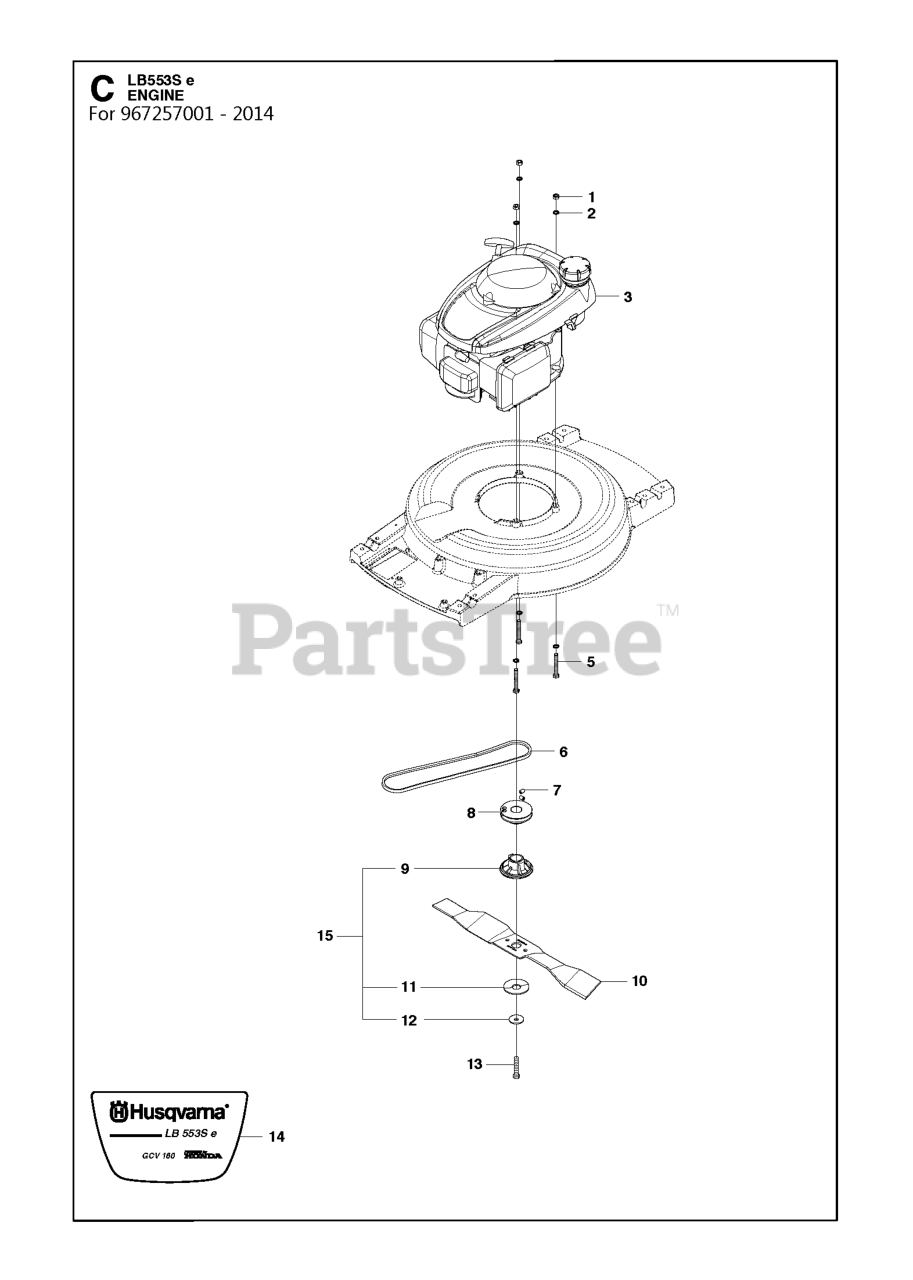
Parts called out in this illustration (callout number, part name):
1	LOCKNUT M8
2	WASHER BRB 8.4X17
6	BELT
9	BLADE SUPPORT
11	SPRING M53 / M48
13	BOLT M53 / M48
